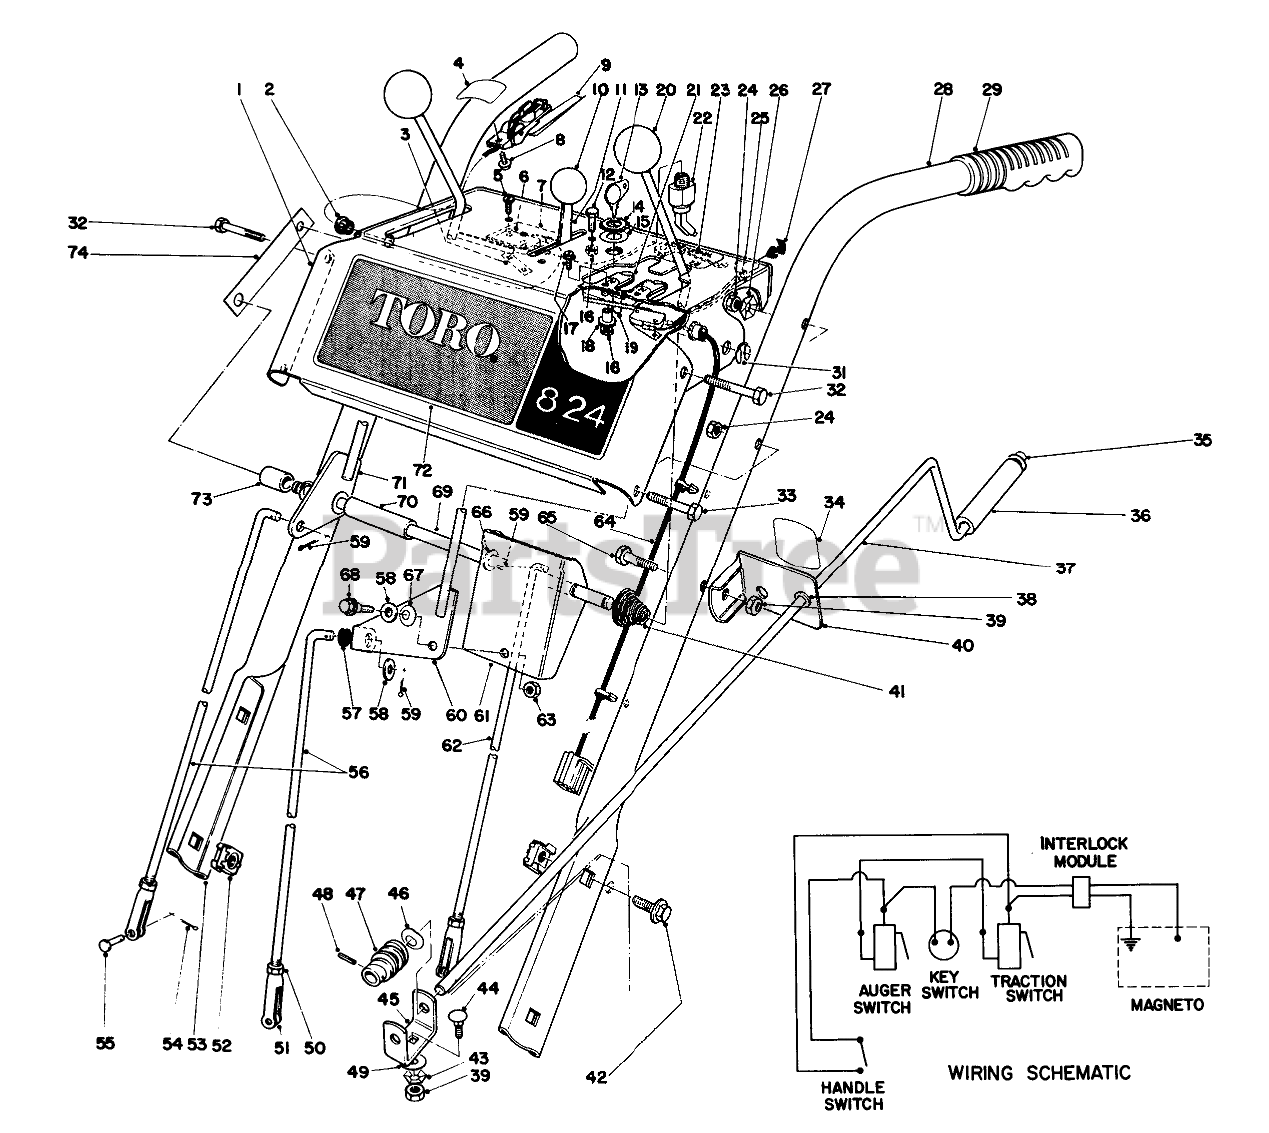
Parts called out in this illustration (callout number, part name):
1	ESCUTCHEON PLT B
2	BUSHING NYLON
3	NUT-SPEED
4	INTERLOCK DECAL
5	SCREW-SPH
6	SWITCH-MICRO
7	SWITCH MTG PAD
8	SCREW
9	INTERLOCK HDLE SWITCH
10	CONTROL KNOB
11	THROTTLE CONTROL
12	HEX HEAD SEMS 10-24X1/2
13	Key
14	NUT-HH
15	WASHER-TOOTH, INTERNAL
16	Nut
17	Screw
18	INTERLOCK SPACER
19	INTERLOCK SPRING
21	Slide Interlock
22	Key Switch
23	INSTRUCTION DECAL
24	NUT-LOCK, CONE
25	WIRE CLAMP
26	Washer
27	Mounting Stud
28	LEFT HANDLE
29	Grip Handle
31	Klip Ring
32	SCREW-HH
33	SCREW-HH
34	CHUTE DECAL
35	RETAINER-PUSH ON
36	GRIP-CONTROL, CHUTE
37	CHUTE CONTROL ROD
38	Bushing
39	NUT-LOCK, NI
40	Chute Control Rod Mounting (Incl. Ref. #34 & 38)
41	CONICAL SPRING
42	SCREW-HHF
43	WASHER-LOCK
44	BOLT-CARR
45	WORM BRACKET
46	WASHER-SPRING
47	GEAR-WORM, CHUTE
48	PIN-SPRING
49	WASHER
50	SCREW-HH
51	TOGGLE
52	Retained Nut
53	HANDLE RIGHT
54	PIN-COTTER
55	PIN-CLEVIS
56	SPEED SELECTOR ROD
57	GROMMET-RUBBER
58	WASHER-FLAT
59	PIN-COTTER
60	SHIFT LEVER WA
61	SHIFT BRACKET
62	TRACTION CONTROL ROD
63	NUT-LOCK, CONE
64	WIRE HARNESS INTERLOC
65	SCREW-HH
66	WASHER-FLAT
67	7/16 SPRING WASHER
68	SHOULDER SCREW
69	PIVOT ROD
70	SHIFT LEVER SPACER
71	LEVER WA
72	ESCUTCHEON DECAL
73	AUGER LEVER SPACER
74	ESCUTCHEON SUPT STRAP
